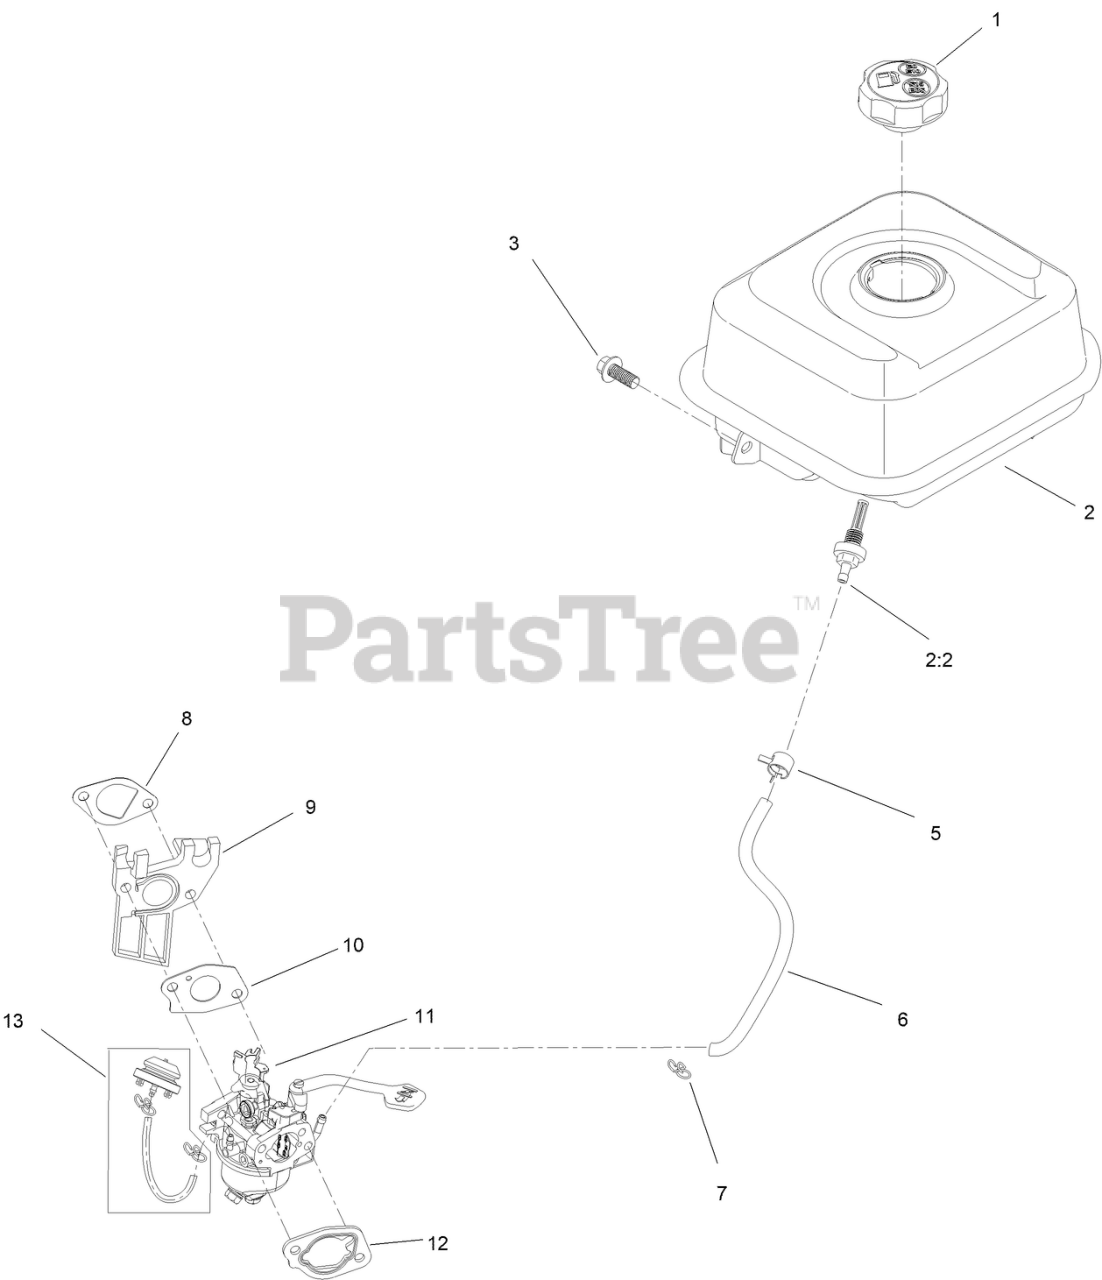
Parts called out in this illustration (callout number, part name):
1	CAP-FUEL
2	FUEL TANK AND FILTER ASM
2:2	FILTER-FUEL
3	SCREW-HHF
5	CLAMP-HOSE
6	HOSE-FUEL
7	CLAMP-HOSE
8	GASKET-CARBURETOR
9	INSULATOR-CARBURETOR
10	GASKET-CARBURETOR
11	CARBURETOR ASM
12	GASKET-CARBURETOR
13	PRIMER KIT
